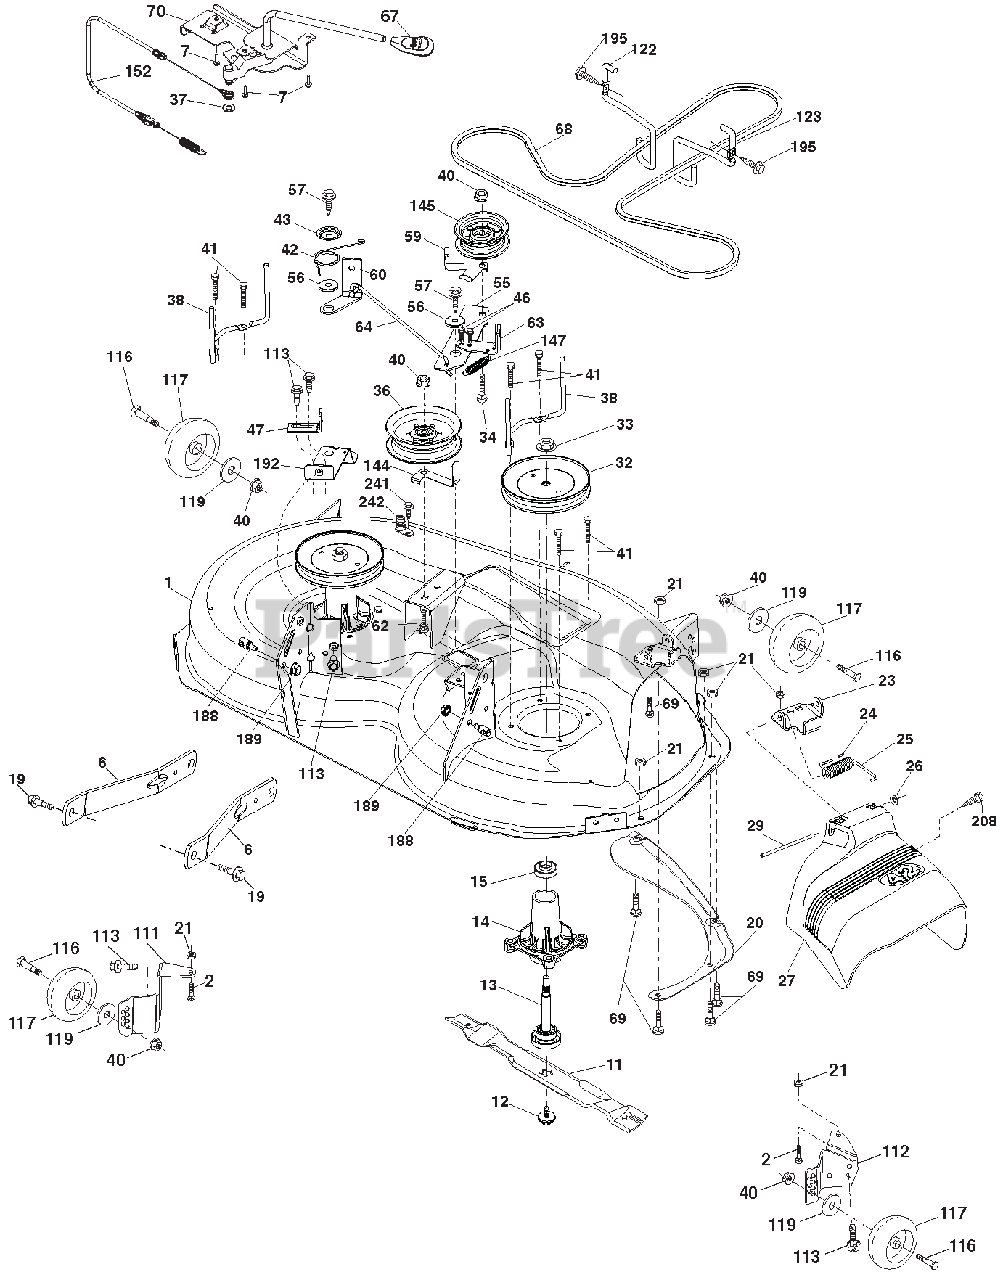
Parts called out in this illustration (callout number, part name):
1	DECK.PNT.WELDMENT.42"
6	ARM.SUSPENSION.MOWER.REAR.LD
11	BLADE.MOWER.42"HI LIFT PREMIUM
12	SCREW 7/16-20 X 1
13	SHAFT ASM
14	HOUSING.MANDREL.4PT.SERVICE
15	BEARING
19	BOLT.SHOULDER
20	BAFFLE.VORTEX.42.STD/HEAVY DTY
21	Nut, Hex, Crownlock 5/16-18
23	BRACKET.DEFLECTOR.38/42"2005
24	CAP.SLEEVE..80X.112.BLK.MOWER
25	SPRING.TORSION.DFL.38/42/46.GR
26	NUT.PUSH.PHOS.& OIL
27	SHIELD.DEFLECTOR.
29	ROD.HINGE.42/46"
32	PULLEY.MANDREL.5.438 PD.42"
32	MANDREL ASM
33	NUT.FLANGE.LOCK.TOP
34	BOLT.CARR.SH.3/8-16X1-1/2.GR5
36	PULLEY.IDLER.4.50.RAW
37	WASHER.13/32 X 13/16 X 16 GA.
38	KEEPER.BELT.MANDREL.PULLEY
40	Nut, Hex, Flangelock 3/8-16
41	HEX HEAD BOLT
42	SPRING.TORSION.BRAKE
43	SPRING.TORSION.RETAINER
46	SCREW.THD.ROLL.1/4-20 X 5/8
47	BRACKET.CLUTCH.CABLE
55	IDLER.ARM
56	SPACER.RETAINER
57	SCREW.3/8-16X1.SMGML.TAP/R.BLK
59	GUARD.TUV.IDLER
60	ARM.BRAKE.MOWER.42"
62	BOLT.RD.HD.SQ.NK.3/8-16UNC X 2
63	ARM.BRAKE.MOWER
64	LINKAGE.BRAKE
67	HANDLE.CLUTCH.CABLE.LT TEX.428
68	BELT.DRIVE.100.97"
69	BOLT.RDHD.SQNK.5/16-18 X 5/8
70	CLUTCH ASM.
111	BRACKET WHEEL GAUGE LH
112	BRACKET WHEEL GAUGE RH
113	BOLT.5/16-18HEX.WHS.HD.LCKSERR
116	BOLD SHLD "A" 2.41 "B" 1.66
117	WHEEL.GAGE.HALF.SPOKED
119	Washer 3/8 x 7/8 x 14 Ga.
122	KEEPER.BELT.ENGINE.LH.LT.TEX
123	KEEPER.BELT.ENGINE.RH.LT.TEX
144	KEEPER.BELT.MOWER
145	PULLEY.IDLER 48"PRIMARY
147	SPRING.RETURN
152	CABLE.CLUTCH.MANUAL
188	STUD.FASTNER.W/'D'ANTI-ROTATIO
189	Nut, Lock Hex Flange 5/16-18 u
192	BRACKET.BRAKE.STAND.LH
195	SCREW.5/16-18X3/4.SMGML.TAP/BL
242	PORT WASHOUT
